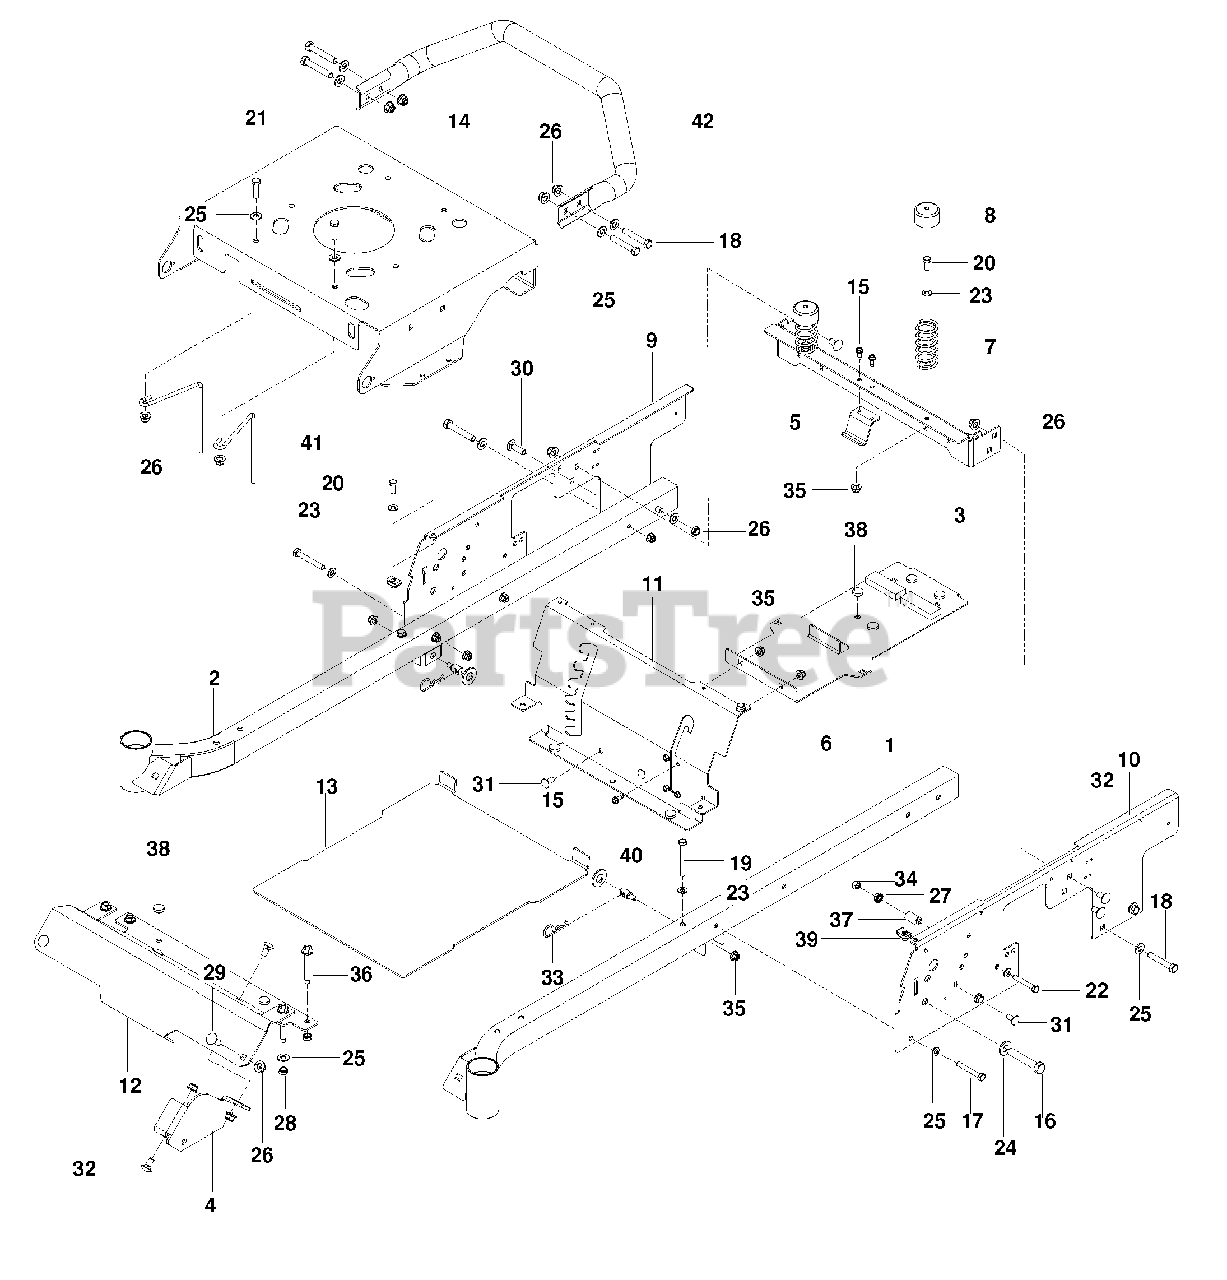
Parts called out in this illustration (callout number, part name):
1	FRAME TUBE, LH ORG
2	FRAME TUBE, RH ORG
3	SUPPORT, REAR SEAT ORG
4	BRACKET, FRONT DECK BLK
5	BRACKET, FUEL TANK BLK
6	SUPPORT, TANK BLK
7	SPRING, SEAT
8	CAP, SPRING
9	PLATE, LH ORG
10	PLATE, RH ORG
11	PANEL, SEAT SUPPORT ORG
12	FOOT REST ORG
13	FOOT PLATE ORG
14	PLATE, ENGINE ORG
15	SCREW 1/4-20 x 5/8 SLF TAP
16	HCS 1/2-13 x 2 3/4
17	HCS 5/16-18 x 2 1/4
18	HCS 3/8-16 x 2 1/4
19	HCS 5/16-18 x 2 3/4
20	HCS 5/16-18 x 3/4
21	HCS 3/8-16 x 1 1/4
22	HCS 5/16-18 x 2
23	WASHER 5/16 SAE FLAT
24	WASHER 1/2 SAE
25	WASHER 3/8 SAE FLT
26	NUT 3/8-16 FLANGE NYLOC
27	NUT 5/16-18 HEX WHIZLK
28	NUT 3/8-16 HEX JAM NYLOC
29	RHSNB 3/8-16 x 1
30	RHSNB 3/8-16 x 11/4
31	RHSNB 5/16-18 x 3/4
32	RHSNB 3/8-16 x 3/4
34	NUT 5/16-18 HEX NYLOC
35	NUT 5/16-18 FLANGE NYLOC
36	BOLT 3/8-16 x 25/8 THD FRM
38	GROMMET, BUMPER
39	RETAINER, U TYPE
40	STUD w/ ANTI-ROTATE
41	GUIDE, BELT
42	BAR, IMPACT ORG
